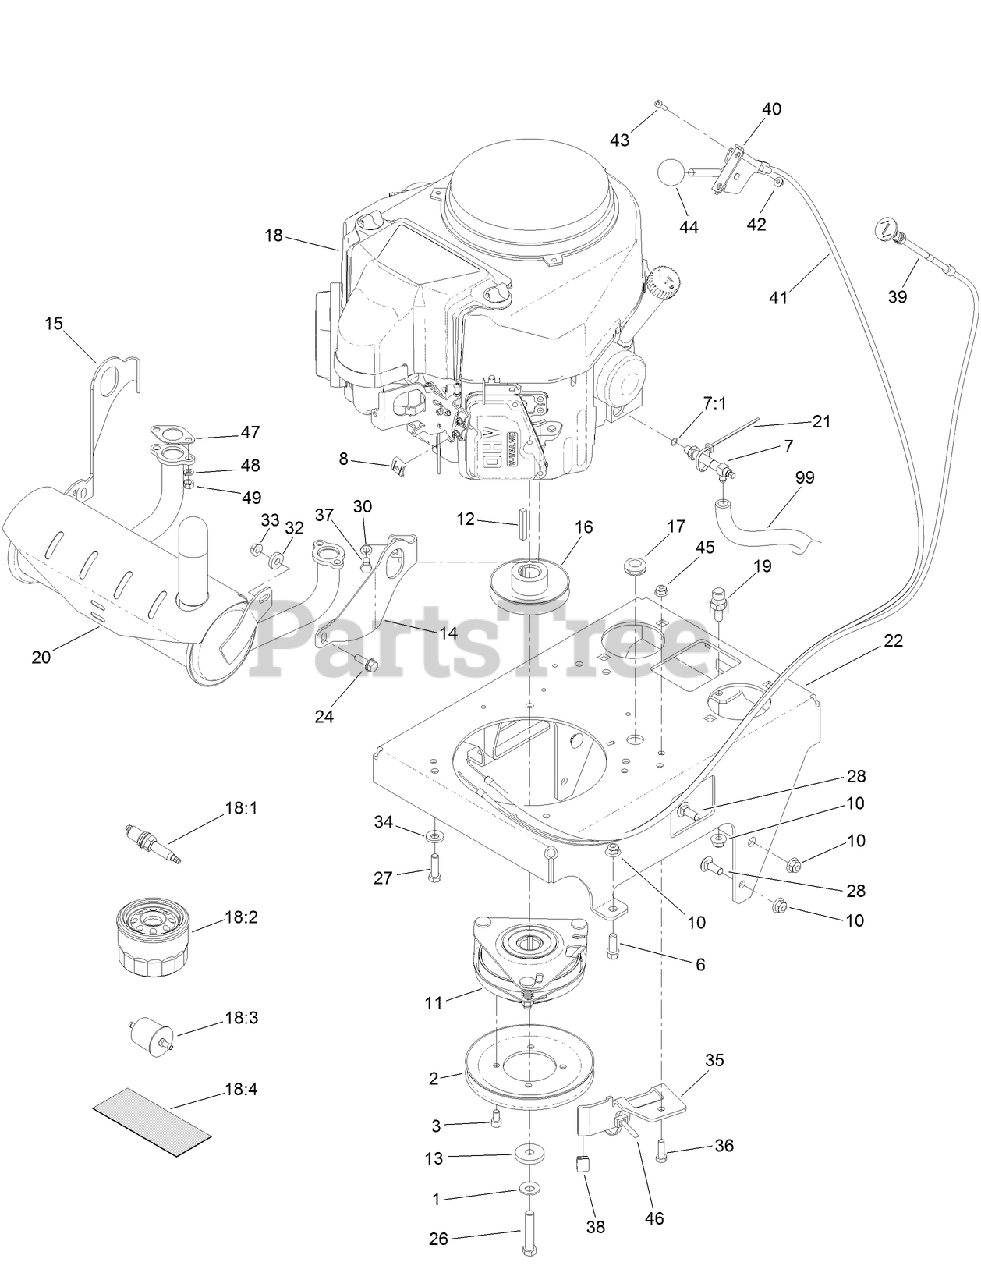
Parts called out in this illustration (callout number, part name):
1	WASHER-SPRING
2	PULLEY
3	SCREW-HSH
7	DRAIN-OIL, VALVE, KAW
7:1	O-RING
8	CLAMP-CABLE
10	NUT-HF, NI
11	CLUTCH/BRAKE ASM
12	KEY-SQUARE
13	WASHER
14	BRACKET-MUFFLER, LH
15	BRACKET-MUFFLER, RH
16	PULLEY
17	GROMMET
18:1	SPARK PLUG
18:2	FILTER-OIL
18:3	FILTER-FUEL
18:4	ELEMENT-FILTER, AIR
19	ANCHOR-SPRING, SHORT
20	MUFFLER
21	TIE-CABLE
22	BASE-ENGINE
24	SCREW-HHF
27	SCREW-HH
28	SCREW-HH
30	SCREW-HH
32	SPACER
33	NUT-HF
34	WASHER-BELLEVILLE
35	BRACKET-CLUTCH STOP
36	SCREW-HH
37	SCREW-HH
38	BUMPER
39	CONTROL-CHOKE, PUSH / PULL
40	LEVER-CONTROL
41	CABLE-CONTROL
42	NUT-LOCK, FLANGE
43	BOLT-CARR
44	KNOB-BALL
45	NUT-HF, NI
46	TIE-CABLE
47	GASKET-EXHAUST
48	WASHER-LOCK
99	HOSE-DRAIN, OIL
